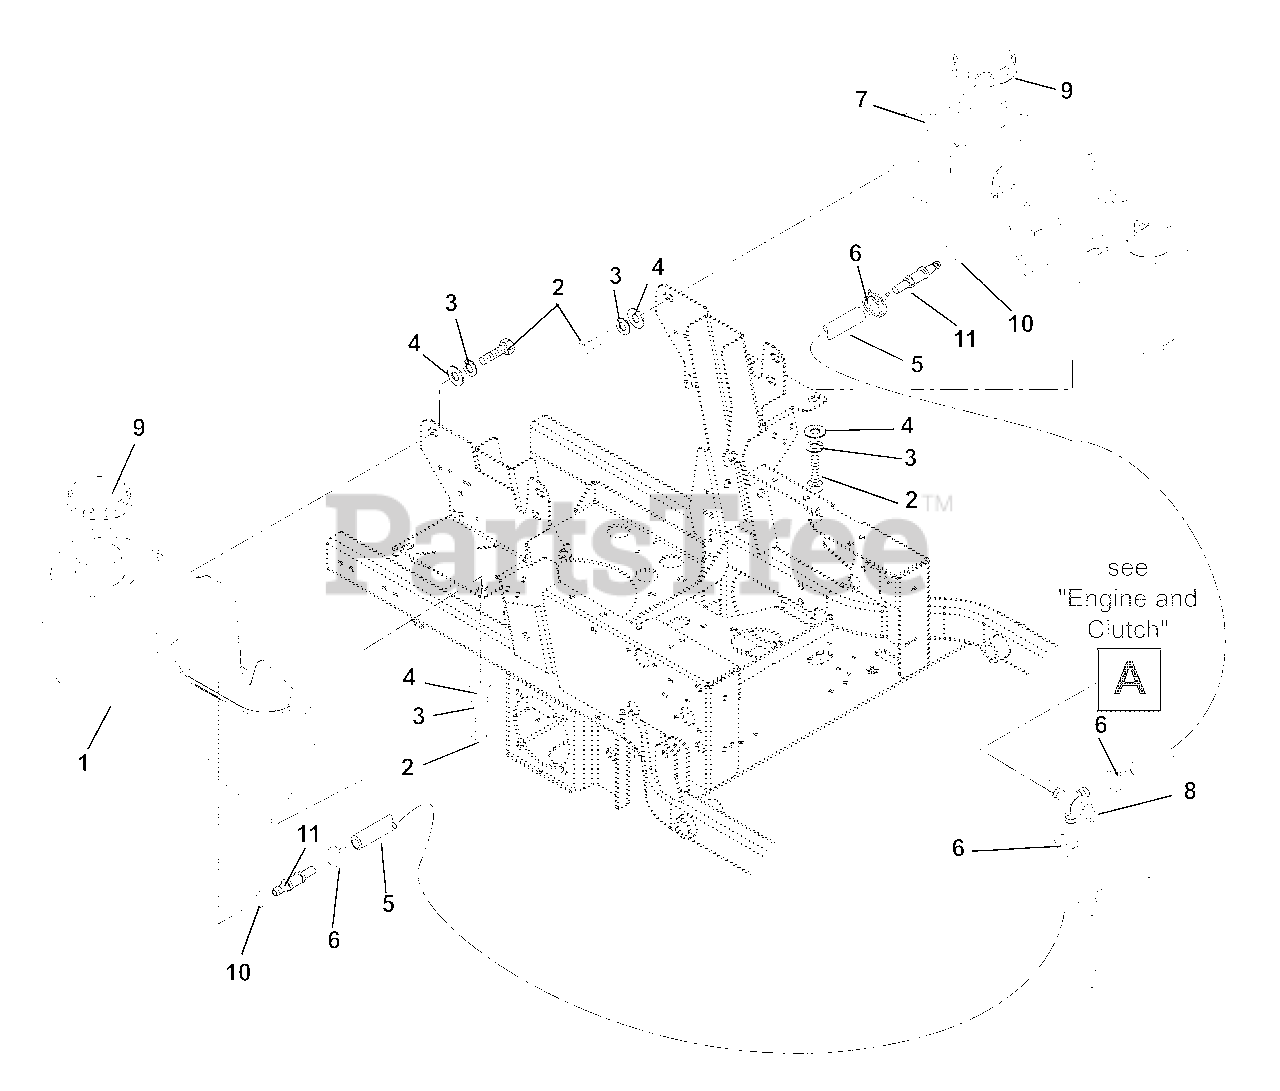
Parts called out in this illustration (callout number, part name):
1	TANK, GAS - RH W/O HOSE
2	@BLT-HEX .31-18X.75 GR5 YWZC
3	@WSHR-LK .31X.078 REG YWZC
4	@WSHR-FL-STL.38X.875X.083 YWZC
5	GAS LINE-BULK 1/4" I.D.
6	CLAMP-HOSE WIRE .490/.510X.116
7	TANK, LH FUEL 100 S. W/O HOSE
8	VALVE, FUEL
9	CAP - FUEL
10	BSHG-FLG .375 X 1.062 X .625 R
11	FITTING, TANK
